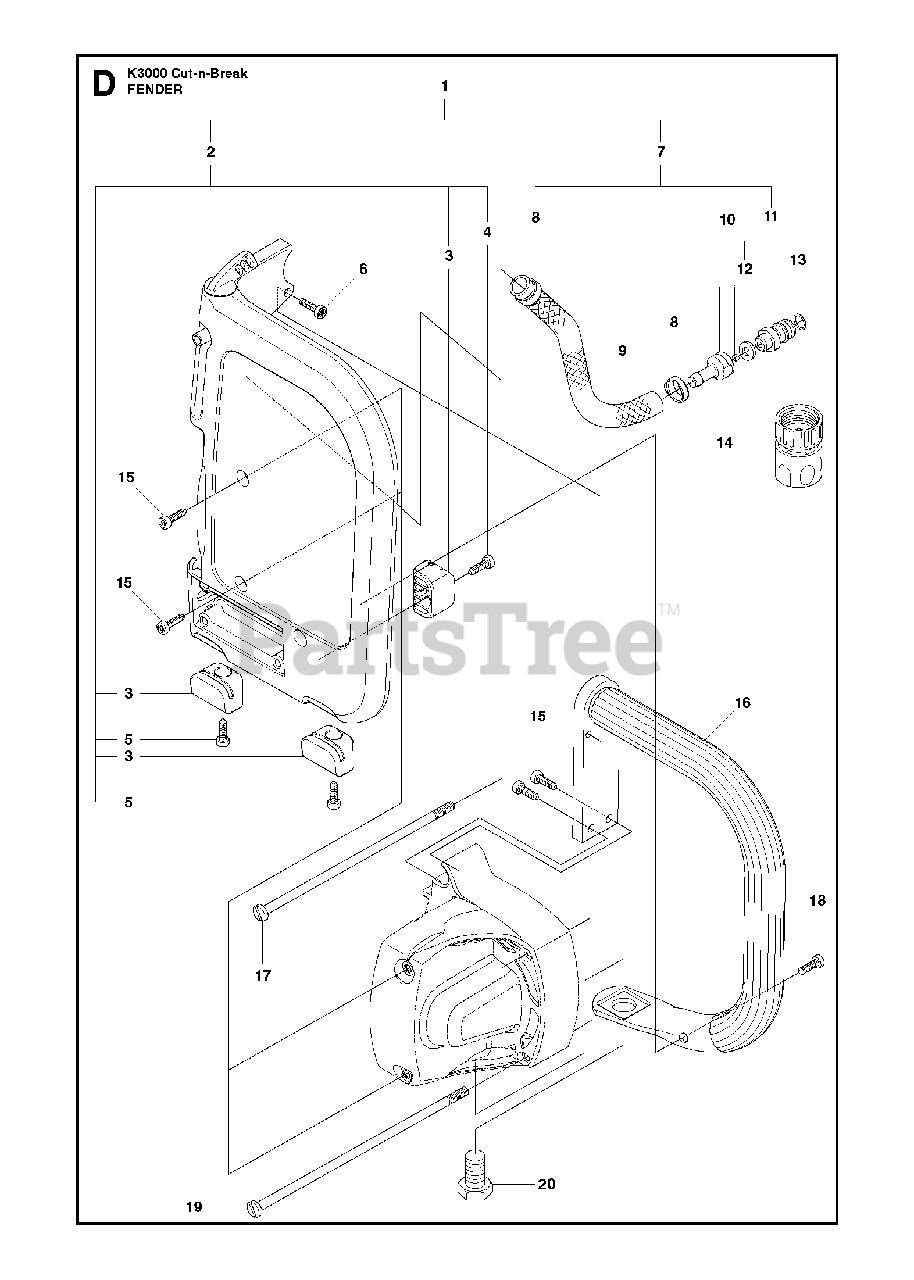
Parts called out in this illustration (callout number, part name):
4	SCREW ITXSCT
5	SCREW ITXSCT
6	SCREW ITXSCM
8	HOSE CLAMP
15	SCREW ITXSCM
18	SCREW ITXSCT
